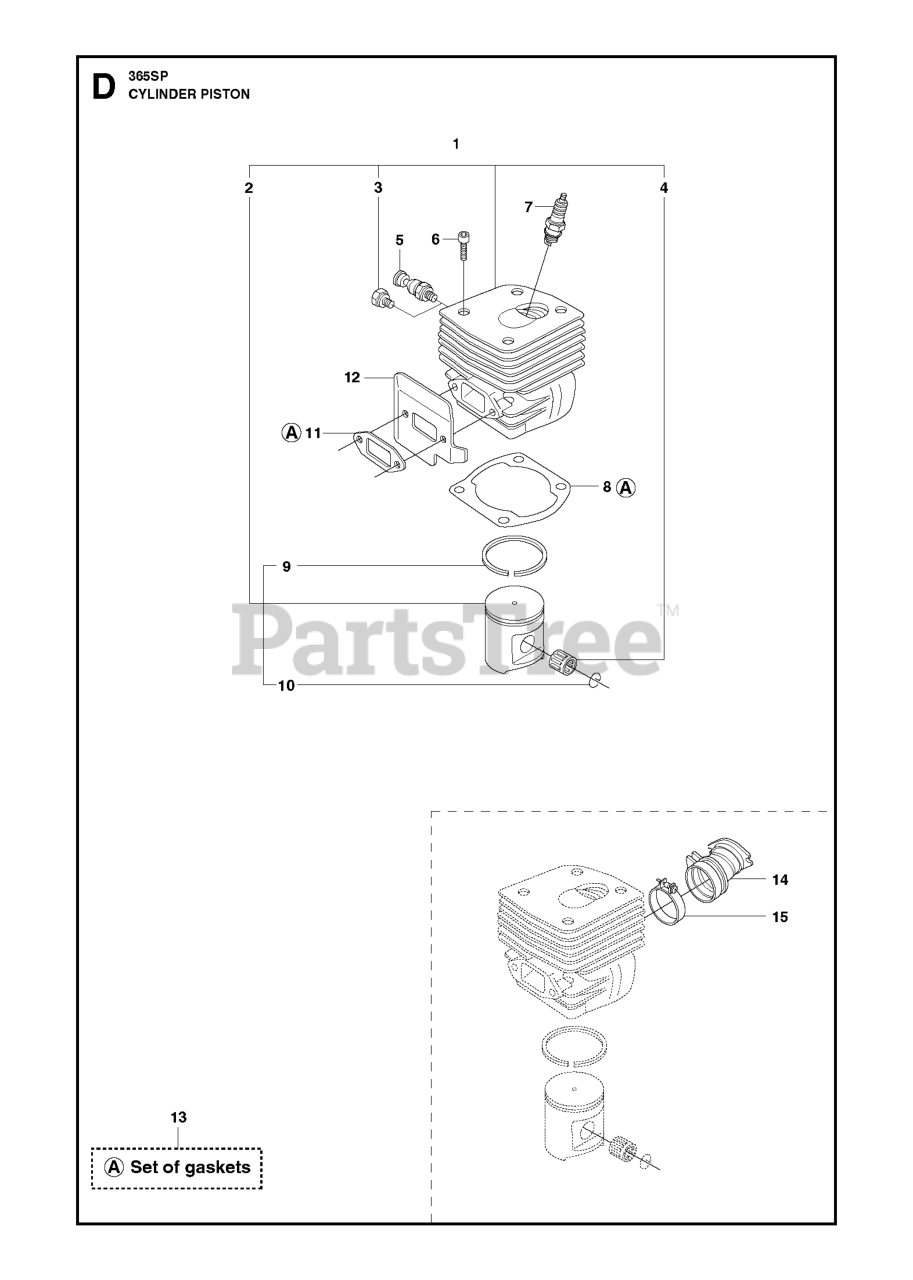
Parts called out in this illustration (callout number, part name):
1	CYLINDER KIT D48
2	PISTON CPL 48 MM
3	CYLINDER PLUG
4	NEEDLE BEARING PISTON PIN 12X1
5	DECOMPRESSION VALVE
6	SCREW MC6S 5X25
7	SPARK PLUG M14X1.25 NGK BPMR7A
9	PISTON RING
10	WRIST PIN CLIP
13	GASKET SET
14	INTAKE PIPE - EPA
15	HOSE CLAMP
